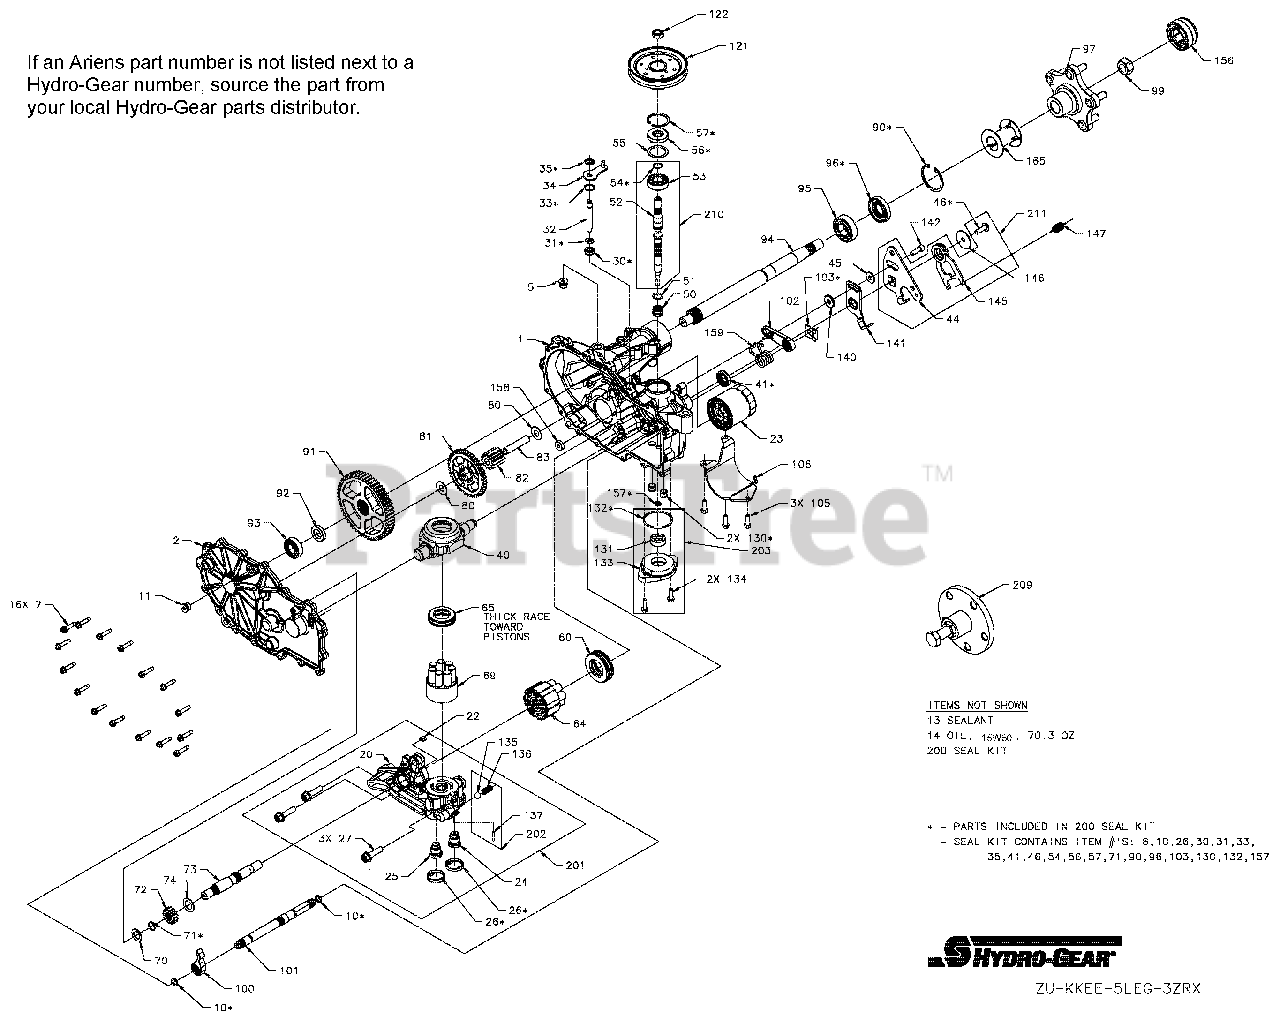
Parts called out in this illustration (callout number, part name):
7	HFHCS 1/4-20 x 1.125"
13	SEALANT
14	SYNTHETIC OIL, 15W50
22	PLATE, BYPASS
23	FILTER, OIL
26	SEAL, PLUG 1.250 x .250
30	SEAL, LIP .375 x .75 x .25
31	RING, RET .375 EXTRNL
33	RING, RET .750 INTRNL
34	ARM, BYPASS
35	RING, RTNG .375 EXT
40	TRUNNION, SWASHPLATE
41	SEAL, LIP 12 x 32 x 7
45	WASHER .34 x .88 x .06
46	TWHCS 5/16-24 x 1.00 (PATCH)
50	SPRING, BLOCK
51	WASHER-FLAT .59 x .79 x .04
55	WASHER 1.23 x 1.56 x .04
56	SEAL, LIP 17 x 40 x 7
57	RING, RETAINING
60	BEARING, THRUST
64	ASS'Y, CYLINDER BLOCK, 16cc
65	BRG, THRUST PLASTIC CAGE
69	ASS'Y, BLOCK 7 PISTON
70	WASHER .63 x 1.0 x .05
71	RING, RETAINING_.625
74	WASHER .72 x 1.16 x .04
80	WASHER .5 x 1.0 x .03
83	JACK SHAFT (PIN)
90	RING, RET 2.06 INT
95	BRG, BALL 25.4 x 52 x 15
96	SEAL, LIP 1.000 x 2.049 x .375
97	KIT, HUB, 5 BOLT
99	NUT, HEX LOCK 3/4-16
103	CLIP, RETAINING
106	GUARD, FILTER, LH
121	PULLEY, 4.5 x 1.625
122	NUT,HEX JAM 1/2-20 W/ PATCH
131	GEROTOR ASSEMBLY (1.9 cc/rev)
132	O-RING, -137, 0.103 x 2.050
140	SPACER .320 x 1.005 x .179
141	ARM, NEUTRAL LEFT
142	SHCS 5/16-24 x 1 PATCH
146	WASHER, .343 x 1.500 x .062
147	SPRING, EXTNSN RTN-34LBS
158	MAGNET, RING
200	KIT, SEAL
201	KIT, CENTER SECTION, LH, CHRG
203	KIT, CHARGE PUMP
210	KIT, INPUT SHAFT
211	KIT, RTN, CCW
